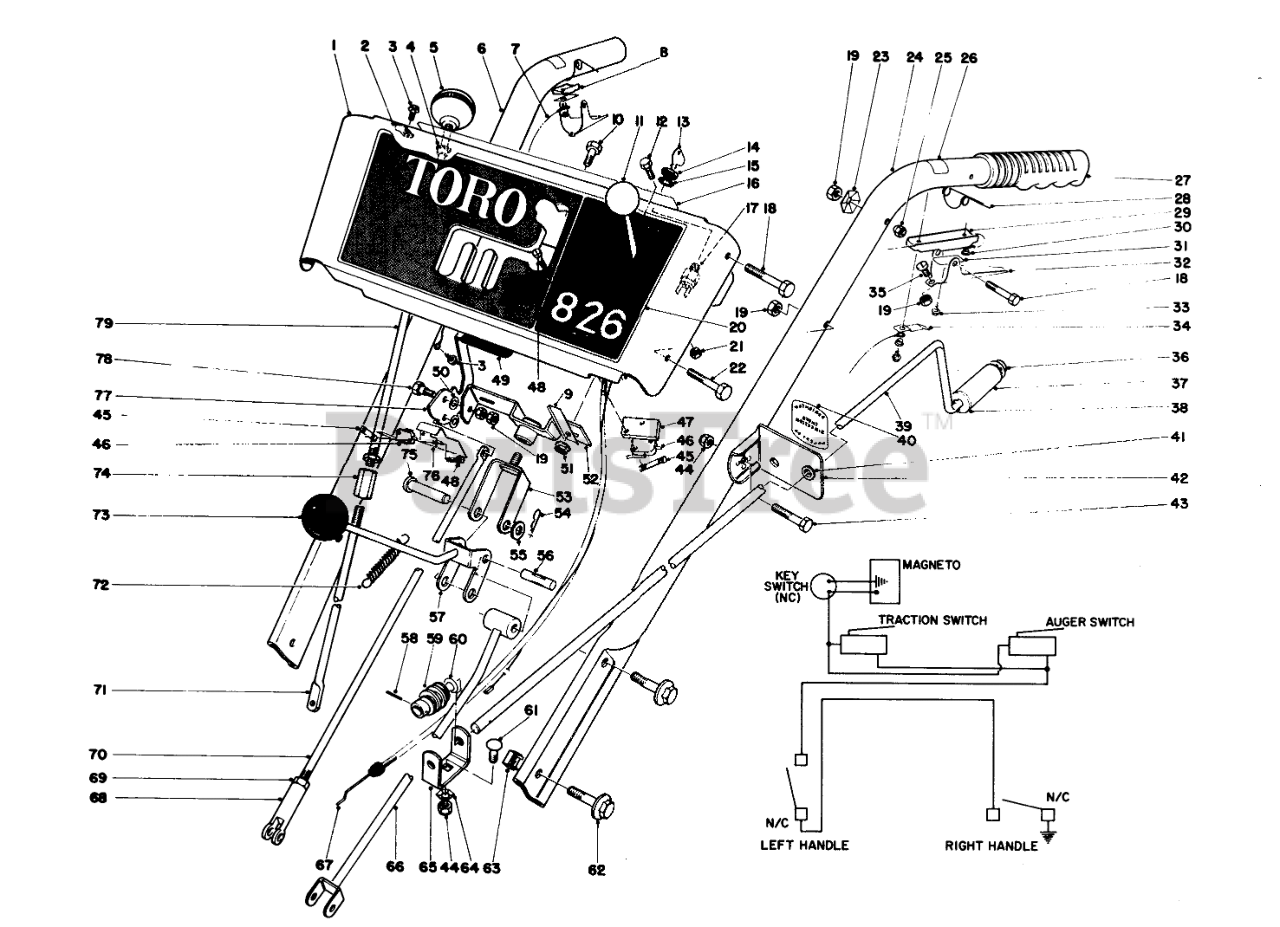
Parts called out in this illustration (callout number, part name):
1	Escutcheon Plate (Model 31763) (Incl. Ref. 1, 16 & 20)
2	PLASTIC CLIP
3	SCREW-HWHTF
4	Bushing
5	KNOB-LEVER
6	Handle Right
7	Wire Harness
8	Insulator
9	Retainer Wire
10	SCREW-HH
11	KNOB-CONTROL
12	HEX HEAD SEMS 10-24X1/2
13	Key (Set of 2)
15	WASHER-TOOTH, INTERNAL
16	Decal Escutcheon Back
17	Switch
18	SCREW-HH
20	Decal Escutcheon (Model 31763)
21	Nut
22	SCREW-HH
23	Washer
24	Handle L.H.
25	NUT-CAP
26	Decal Safety Interlock
27	Grip Handle
28	INTERLOCK SPRING
29	DUAL BRKT INSULATOR
30	WASHER INSULATOR
31	INTERLOCK CONTACT
32	SAFETY INTRLOCK LEVER
33	Screw
34	CONTACT BRACKET
35	NYLON SCREW 1/4 20
36	RETAINER-PUSH ON
37	CHUTE CONTROL GRIP
38	WASHER-FLAT
39	ROD CHUTE CONTROL
40	Decal Chute Direction
41	Bushing
42	Bracket Chute Control Mounting (Incl. Ref. #40 & 41)
43	SCREW-HH
44	NUT-LOCK, CONE
45	Speed Nut
46	MICRO SWITCH
47	SWITCH MTG PAD
48	SCREW-SPH
49	AUGER CLUTCH HND GRIP
50	WASHER-PLAIN
51	NUT-LOCK, HHF
52	SWIVEL BLOCK WA
53	Pivot Bracket
54	PIN-HAIR
55	WASHER-FLAT
56	3/8 X 1-1/4 ROL
57	SHIFT ROD WA
58	PIN-SPRING
59	GEAR-WORM, CHUTE
60	Spring Washer
61	SCREW-CARR
62	SCREW-HHF
63	Retained Nut
64	WASHER-LOCK
65	WORM BRACKET
66	Trunnion
67	Throttle Contrl
68	Clevis
69	NUT-HJ
70	DRAG LINK
71	LOWER WHL CLUTCH ROD
72	CONT ROD SPRING 0
74	WHL ROD COUPLING
75	PIN-CLEVIS
76	SWITCH BRKT
77	Auger Clutch Handle
78	SCREW-SHOULDER
79	Rod Wheel Clutch
